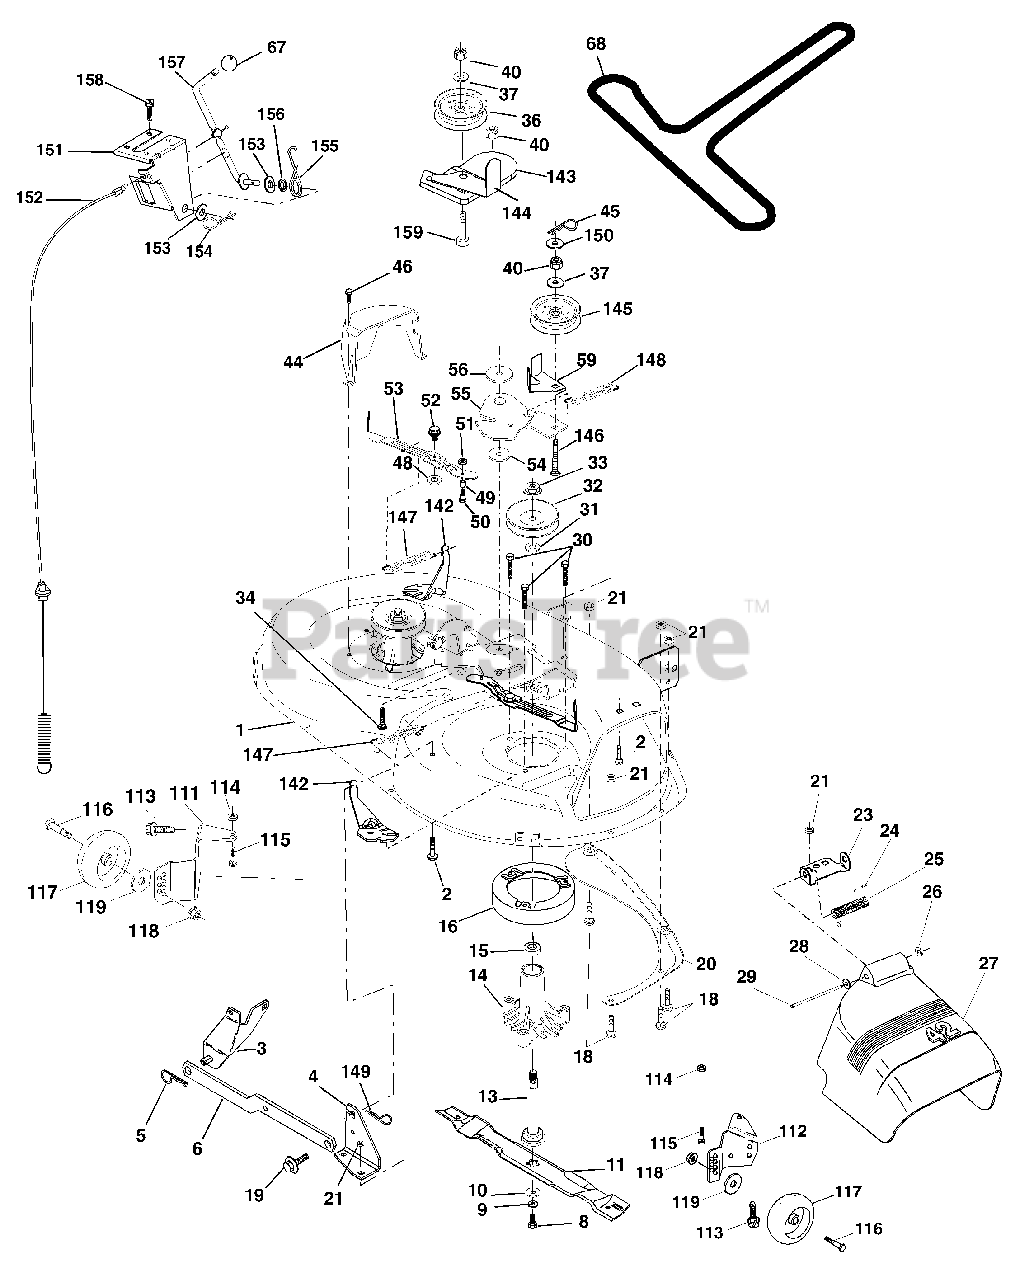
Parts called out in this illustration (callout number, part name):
1	Deck Asm MWR 42" weldment
2	Bolt Rdhd Sqnk 5/16-18unc X 3/4
3	Bracket Asm Fr Sway Bar 38/42
4	Bracket Asm Deck 42" sway Bar
5	Retainer Spring
6	Deck Sway Bar
8	Bolt 3/8 - 24 X 1.25 Gr 8
9	Washer Lock Hvy 3/8
10	Washer Hard Blade Mower Vented
11	Blade Mower 42"
13	Shaft Asm W/lower Bearing
14	Housing Mandrel Vented
15	Bearing Ball Mandrel
16	Stripper Mower
18	Bolt Rdhd Sqnk 5/16-18 X 5/8
19	Bolt Shoulder
20	Baffle Vortex 42
21	Nut Crownlock 5/16-18 UNC
23	Bracket Deflector Mower 42"
24	Cap Sleeve 80 x 112 Blk Mower
25	Spring Torsion Deflector 2 52
26	Nut Push Phos & Oil
27	Shield Deflector Mower 42" Blk
28	Washer 11/32 X 5/8 X 16 Ga
29	Rod Hinge 42" 6 75 Wlg
30	Screw Thd Rolling
31	Washer Spacer Mower Vented
32	Pulley Mandrel 42"
33	Nut Toplock Flng
34	Bolt Rdhd 3/8-16 unc x 1-3/4 Gr5
36	Pulley Idler Flat 3 060
37	Washer 13/32 X 13/16 X 16
40	Nut Crownlock 3/8-16 UNC
44	Guard Mandrel LH Black
45	Spring Retainer 1" Zinc/cad
46	Screw Hex Thd Cut 1/4-20 x 5/8 T
48	Washer Hardened Smaller
49	Roller Asm Cam Follower 42" Deck
50	Bolt Shldr 10-24 Zinc Gr 5 42"
51	Nut Lock #10-24 Unc
52	Bolt Shoulder 5/16-18 Unc Blkz
53	Arm Asm Pad Brake
54	Washer Hardened
55	Arm Idler 42" mower LT/YT
56	Spacer Retainer Mower
59	Guard TUV Idler
67	Knob Rd 3/8-16 Plstc Thds Blk
68	V-Belt Mower 42"
111	Bracket Wheel Gauge LH 42" Deck
112	Bracket Gauge Wheel RH 42" Deck
113	Screw Tapping 3/8-16 x .625
114	Nut Keps 5/16-18 Unc
115	Bolt Carriage 5/16-Unc x 5/8
116	Bolt Shoulder
117	Wheel Gauge
118	Nut Centerlock 3/8-16 UNC
119	Washer 3/8 x 7/8 x 14 Ga.
142	Arm Spring Brake Mower
143	Bracket Arm Idler 42"
144	Keeper Belt 42" Clutch
145	Pulley Idler Flat
146	Bolt Carriage Idler
147	Spring Extension
148	Spring Return Idler
149	Retainer Spring Yellow
150	Washer 9/32 x 3/4 x 16 Ga.
151	Bracket Clutch Cable
152	Clutch Cable 42"
153	Washer Flat 3/8" Type B
154	Spring Retainer
155	Spring Retention Lvr Cltch Cab
156	Spacer Clutch Cable
157	Rod Clutch Cable 3/8"
158	Screw Hex Thd Cut 1/4-20 x 1/2
159	Bolt Rdhd Sqn 3/8-16 Unc x 1-3/4
